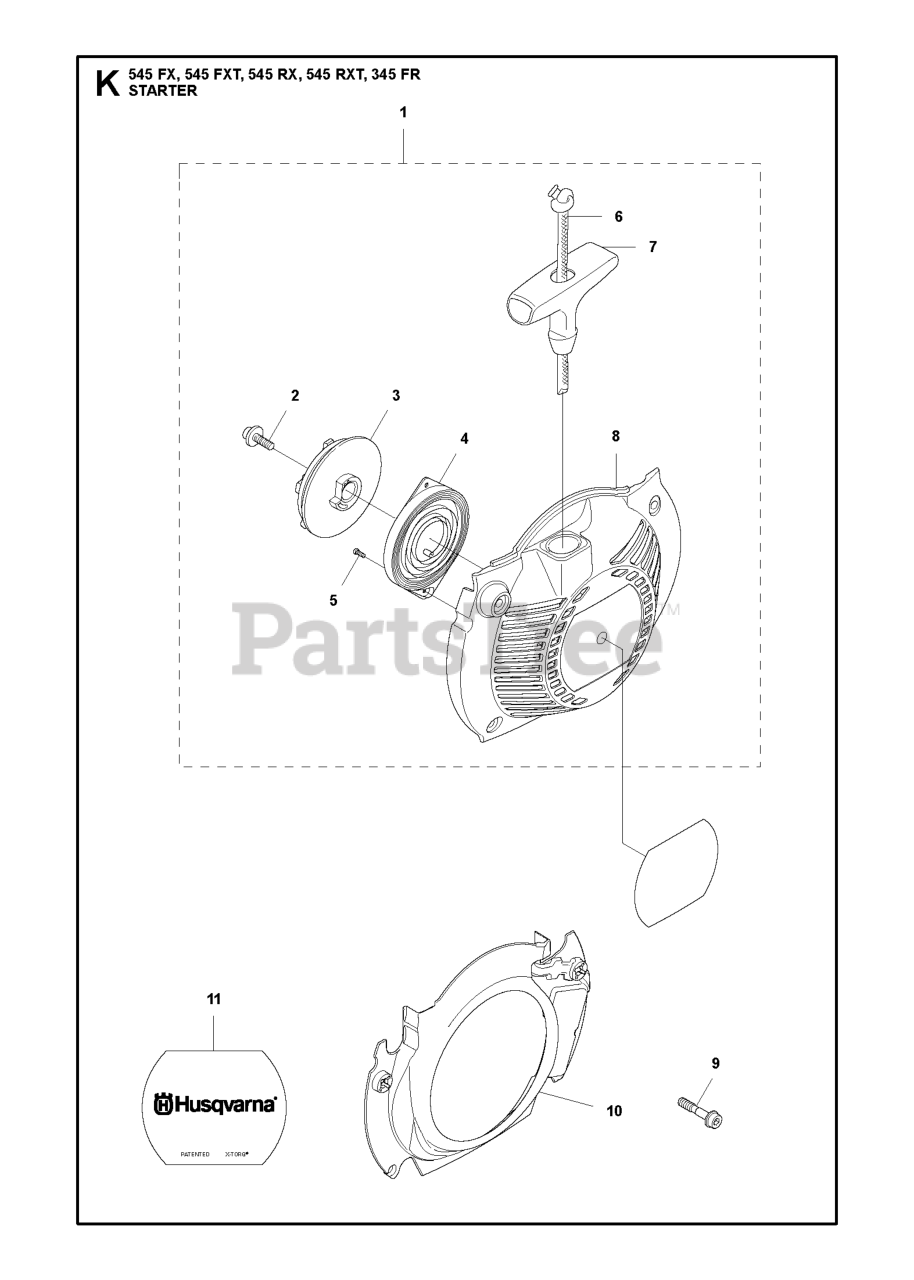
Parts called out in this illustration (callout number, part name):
2	SCREW
3	STARTER PULLEY
4	RECOIL SPRING
5	SCREW
6	STARTER ROPE
7	HANDLE
8	STARTER HOUSING
9	SCREW IHSCFMO
10	COOLING AIR CONDUCTOR
